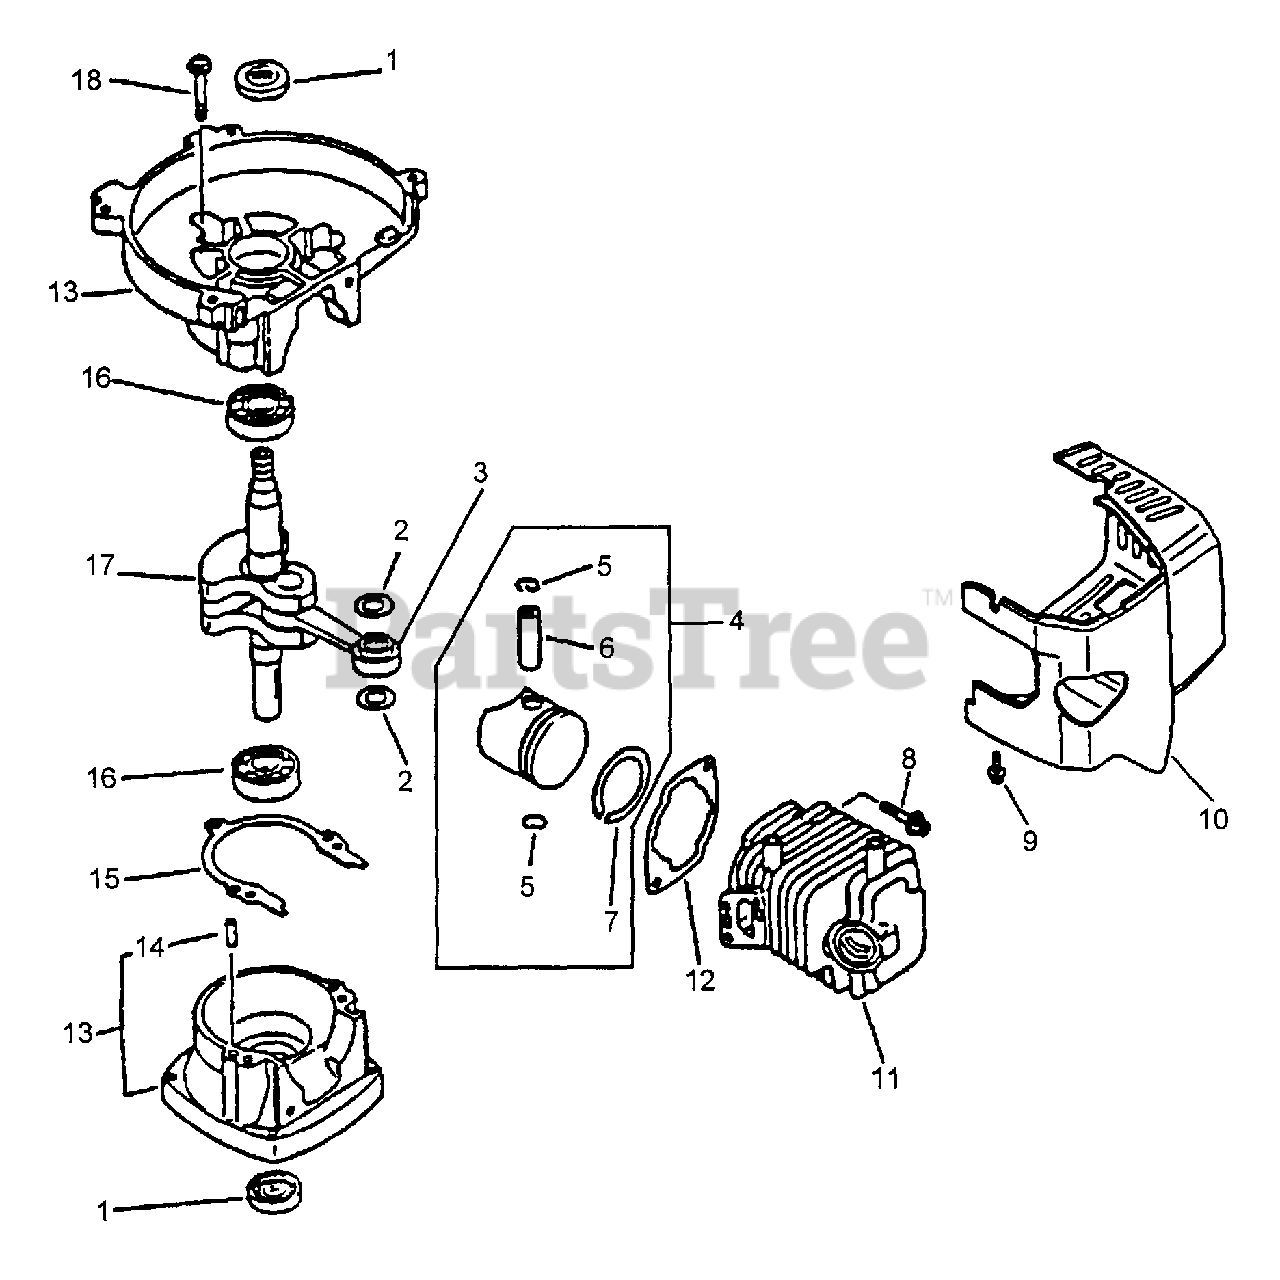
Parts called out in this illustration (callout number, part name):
1	SEAL, OIL
2	SPACER, PISTON
2	WASHER
3	BEARING, NEEDLE
3	BEARING, NEEDLE - 8
4	PISTON KIT
5	RING, RETAINING
6	PIN, PISTON
7	RING, PISTON
8	SCREW - 5X22
9	SCREW - 4X20
10	ENGINE COVER KIT - GRAY
10	COVER, ENGINE
11	CYLINDER
12	GASKET, CYLINDER
13	CRANKCASE KIT
14	PIN - LOCATING
15	GASKET, CRANKCASE
16	BEARING, BALL - 6201
17	CRANKSHAFT ASSY
18	SCREW - 5X28
